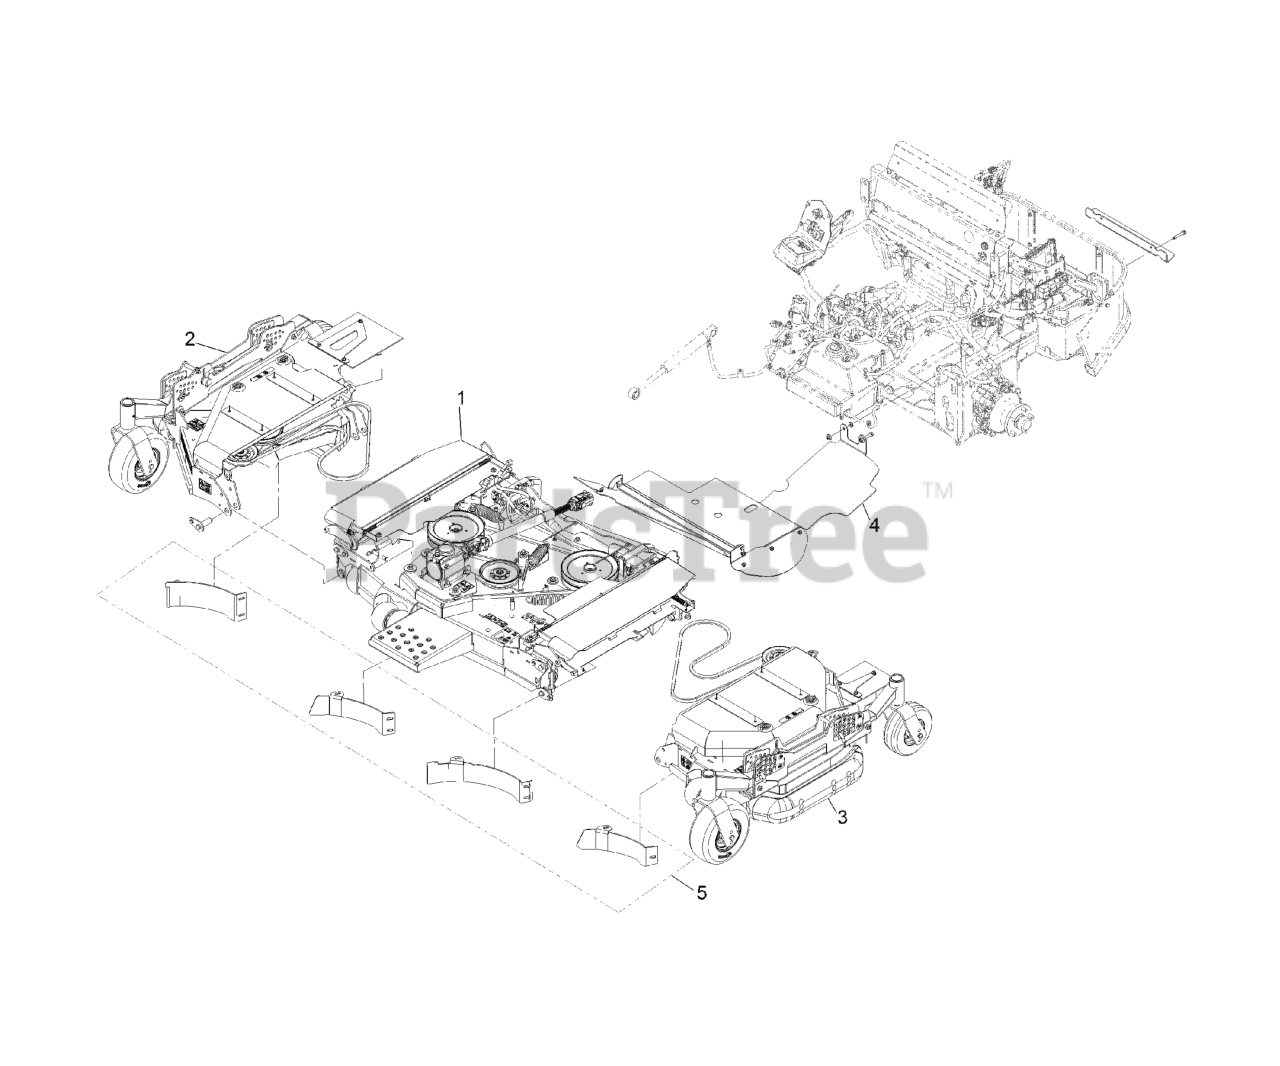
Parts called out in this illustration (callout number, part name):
1	ASM-DECK, CTR 96
2	ASM-DECK, RH WING 96
3	ASM-DECK, LH WING 96
4	Discharge Tunnel ASM
5	KIT-96RD MULCH
